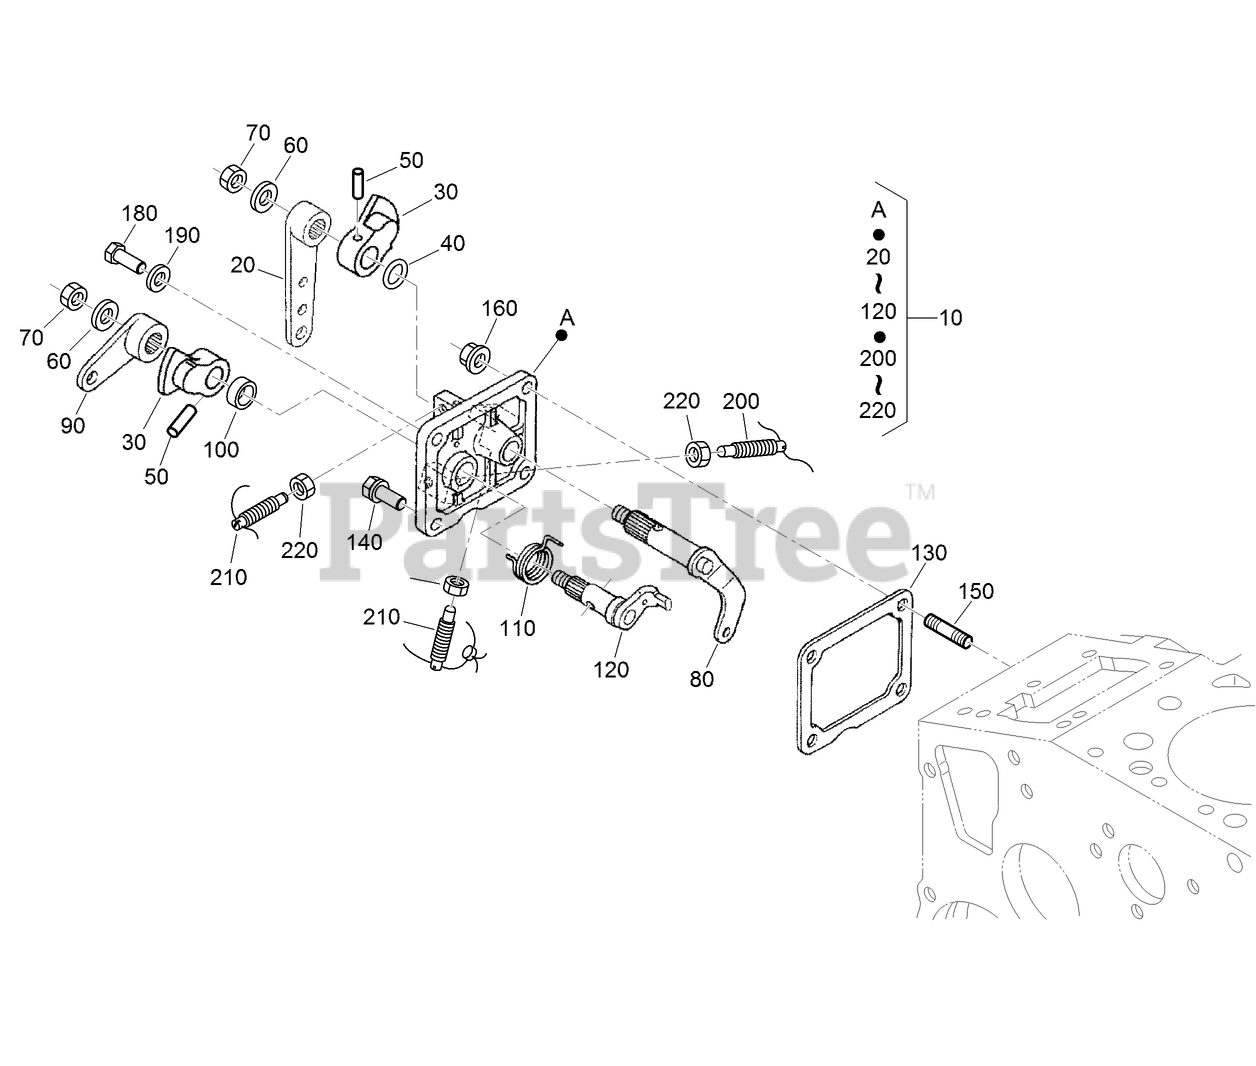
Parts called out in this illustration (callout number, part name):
10	CONTROL PLATE ASM
20	LEVER-CONTROL, SPEED
30	LEVER-CONTROL, SPEED
40	O-RING
50	PIN-SPRING
60	WASHER-PLAIN
80	GOVERNOR LEVER ASM
90	LEVER-STOP, ENGINE
100	SEAL-OIL
110	SPRING-RETURN
120	SHAFT-LEVER, STOP
130	GASKET
160	NUT-FLANGE
180	BOLT-HEX
190	GASKET
200	BOLT-ADJUSTING
210	BOLT-ADJUSTING
